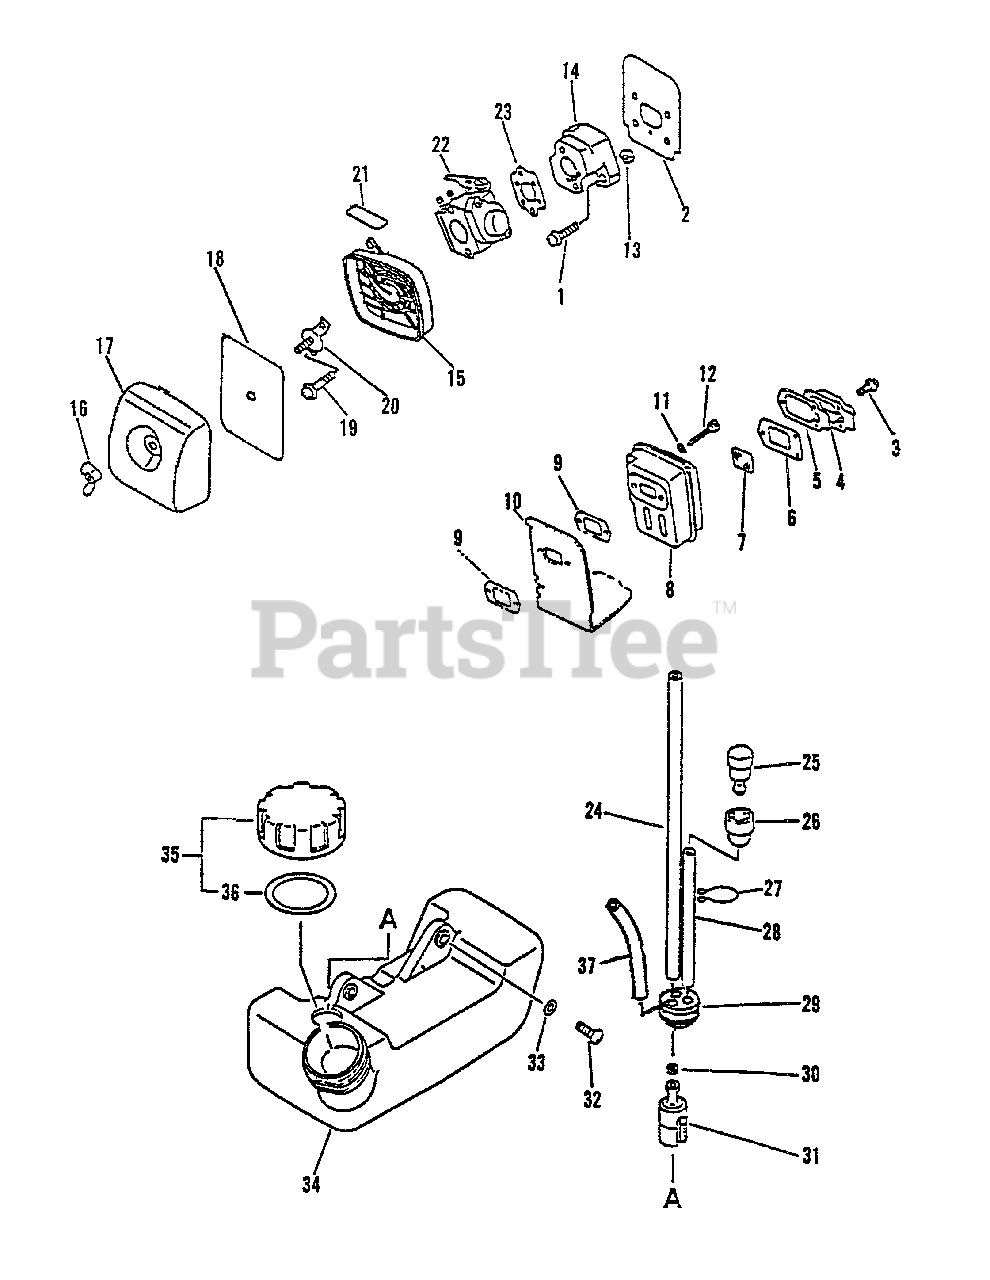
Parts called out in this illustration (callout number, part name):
1	SCREW - 5X22
2	GASKET, INTAKE
3	SCREW - 4X10
4	GUIDE, EXHAUST - INNER
5	GASKET, EXHAUST - INNER
6	GASKET, EXHAUST
7	SCREEN, SPARK ARRESTOR
8	MUFFLER ASSY
9	GASKET, EXHAUST
10	SHIELD, EXHAUST
11	WASHER - 5
12	SCREW - 5X55
14	INSULATOR, INTAKE
15	AIR FILTER CASE ASSY
16	WINGNUT - 6
17	COVER, AIR FILTER
18	FILTER, AIR
19	SCREW - 5X65
20	PLATE, PREVENT
21	LABEL - CHOKE
22	CARBURETOR C1U-K32
23	GASKET, INTAKE
24	PIPE - 3X5X180 -- BLACK
25	VENT, FUEL TANK
26	COVER, VENT
28	PIPE - 3X5X70 -- BLACK
29	GROMMET
30	CLIP - 6
31	FILTER, FUEL
32	SCREW - 5X16
33	WASHER - 5
34	TANK, FUEL
35	CAP ASSY
36	GASKET, CAP
37	PIPE - 3X6X90 -- CLEAR
